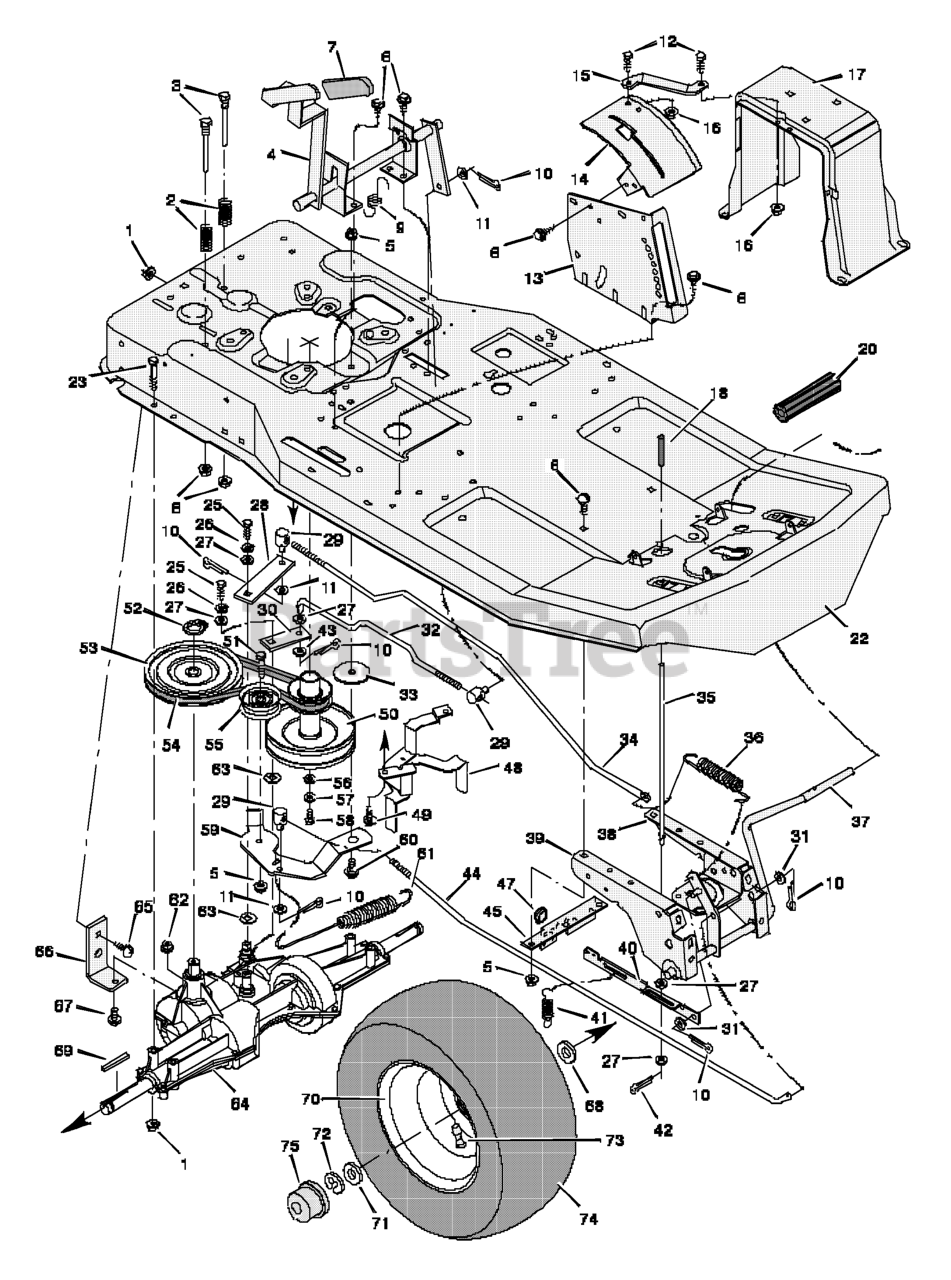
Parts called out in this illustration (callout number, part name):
1	Locknut, Flange
2	Spring, Compression
3	Guide, Belt
4	Shifter Assembly
5	Locknut, Flange
7	Grip, Shift Lever
8	Hex Nut
9	Spring, Extension
10	Pin, Cotter
11	Washer
12	Bolt, Hex
13	Plate, Index
14	Gate, Shift
15	Brace, Shift Gate
16	Locknut, Flange
17	Support, Seat
18	Grip, Parking Brake
20	Pedal, Rubber
22	Frame Assembly
23	Bolt, Hex
25	Bolt, Hex
26	Lockwasher
28	Yoke, Brake
29	Nut, Adjusting
30	Yoke, Shift
31	Washer
32	Rod, Shift
33	Washer, Hardened
34	Rod, Brake
35	Rod, Parking Brake
36	Spring, Extension
37	Lever, Pedal
38	Plate, Left Suspension
39	Plate, Right Suspension
40	Link, Parking Brake
41	Spring, Extension
42	Pin, Cotter
44	Rod, Clutch
45	Stop, Parking Brake
47	Grommet
48	Guide, Belt
50	Pulley Assembly, Stack
51	Bolt, Hex
52	Ring, Retainer
53	Pulley, Drive
54	Belt, Motion Drive
55	Pulley, Idler
57	Lockwasher
58	Bolt, Hex
59	Bracket, Idler
60	Bolt, Shoulder
61	Spring, Extension
62	Locknut, Hex
64	Transaxle, Dana Model 4450-1 **
65	Bolt, Carriage
66	Bracket, Transaxle
67	Bolt, Hex
69	Key, Square
70	Wheel & Tire Assembly
73	Valve Stem
74	Tire *
75	Hub Cap
